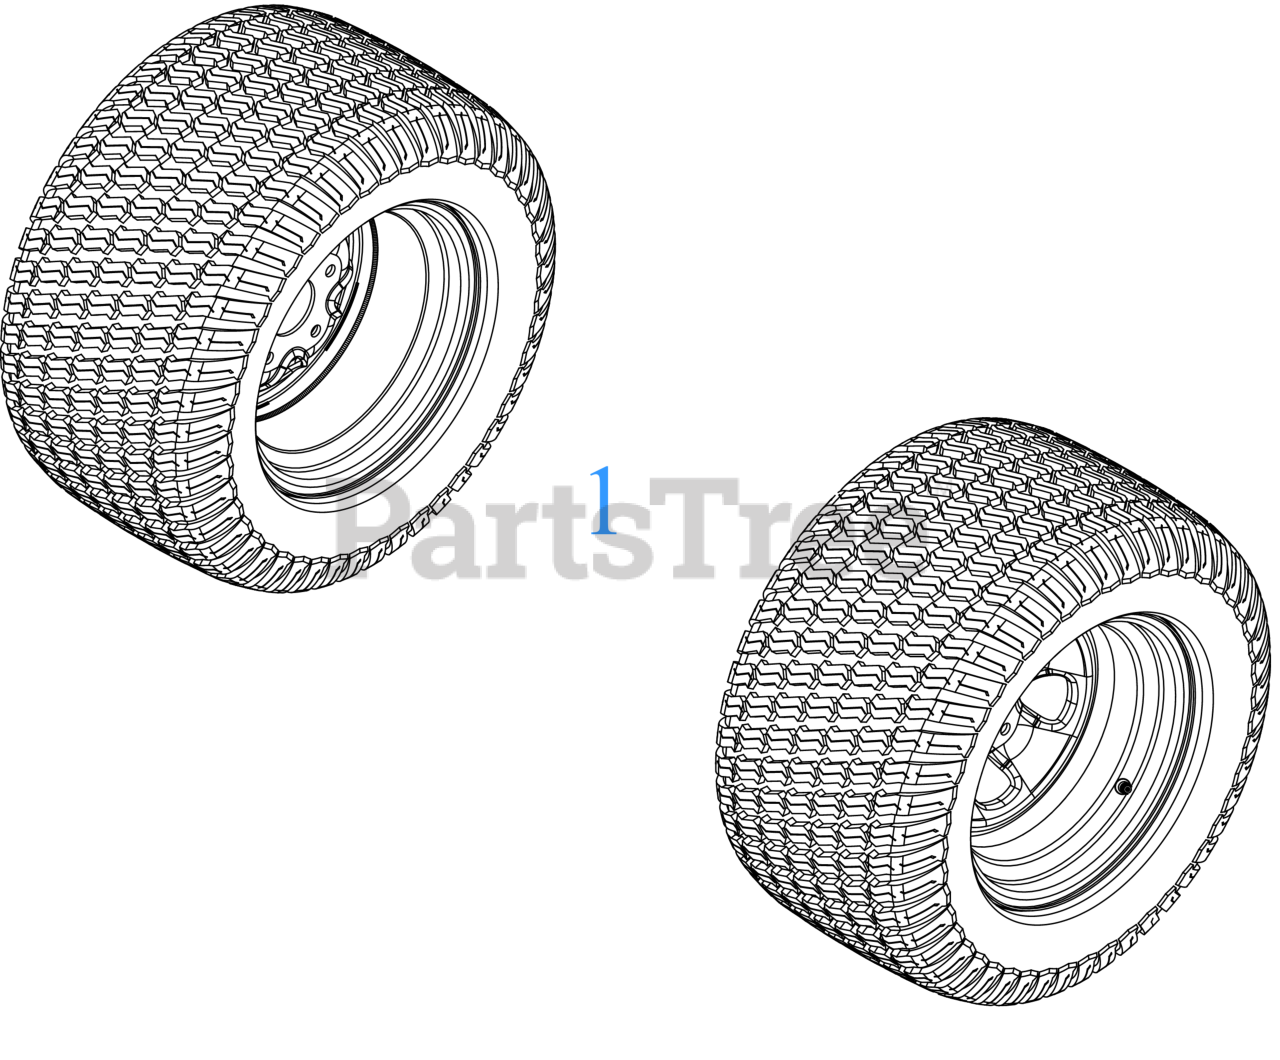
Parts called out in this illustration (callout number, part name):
1	WHEEL ASSEMBLY (22x12-12) (TURFMASTR)
1	RIM ASSEMBLY (12x9)
1	TIRE (22x12-12) (4PLY) (TURFMASTR)
1	TUBELESS AIR VALVE
